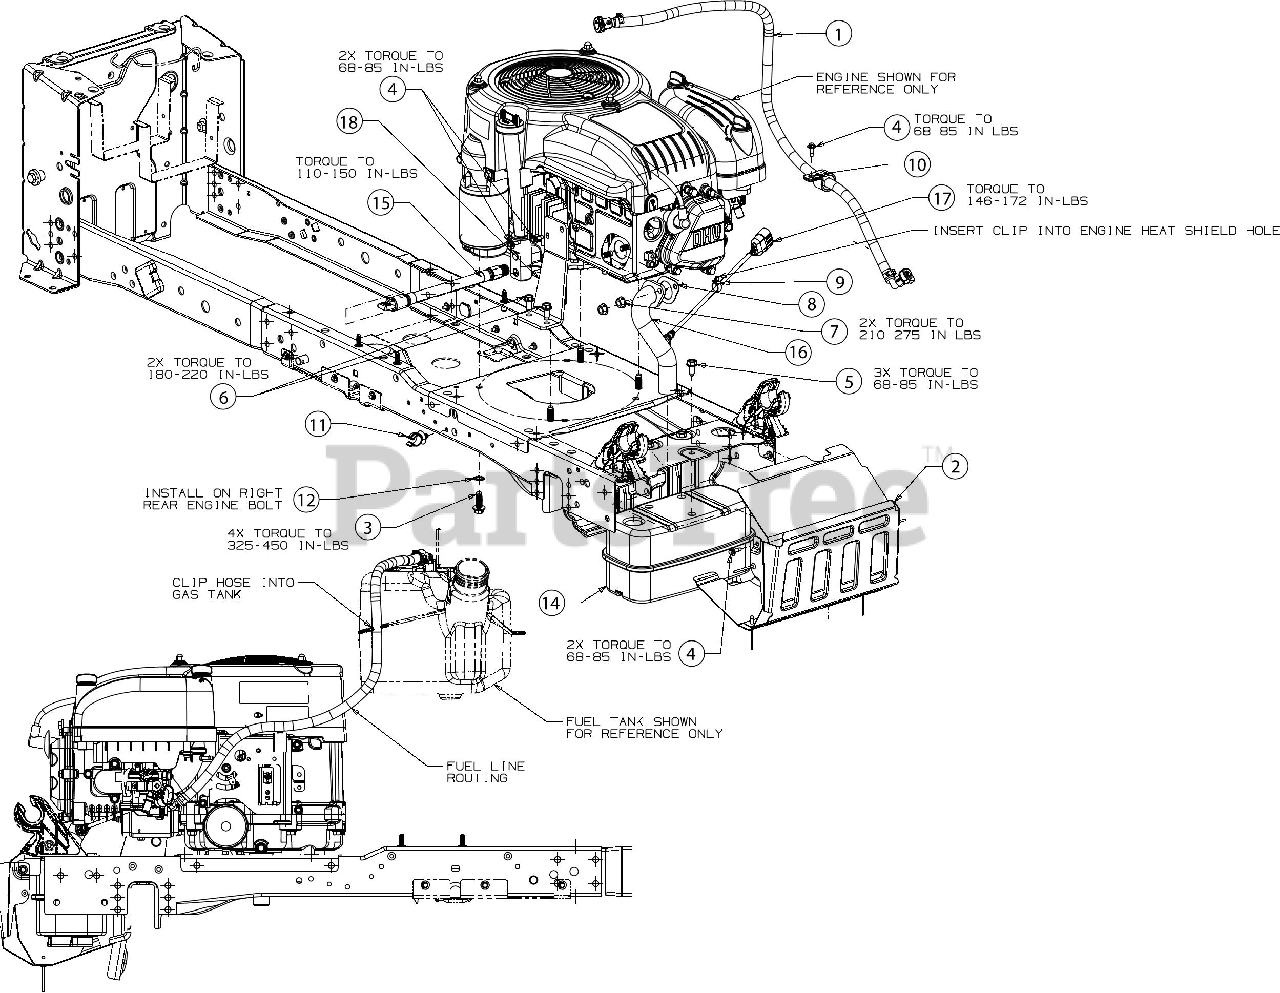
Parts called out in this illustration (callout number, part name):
1	HOSE ASSEMBLY
2	MUFFLER SHIELD ASSEMBLY
2	RIVET - 3/16"
3	SCREW 3/8-16 x 1
4	SCREW M6-1 x .625
5	SCREW M8-1.25 x .750
6	SCREW 5/16-18 x .750
7	HEX FLANGE NUT M8X
8	EXHAUST GASKET
9	FUEL LINE SUPPORT CLAMP
10	HOSE CLAMP 1.0"
11	DRAIN HOSE CLIP
12	LOCK WASHER 3/8
14	EXHAUST MUFFLER (SINGLE)
15	OIL DRAIN HOSE 3/8 NPT
16	EXHAUST PIPE
17	OXYGEN SENSOR ASSEMBLY
